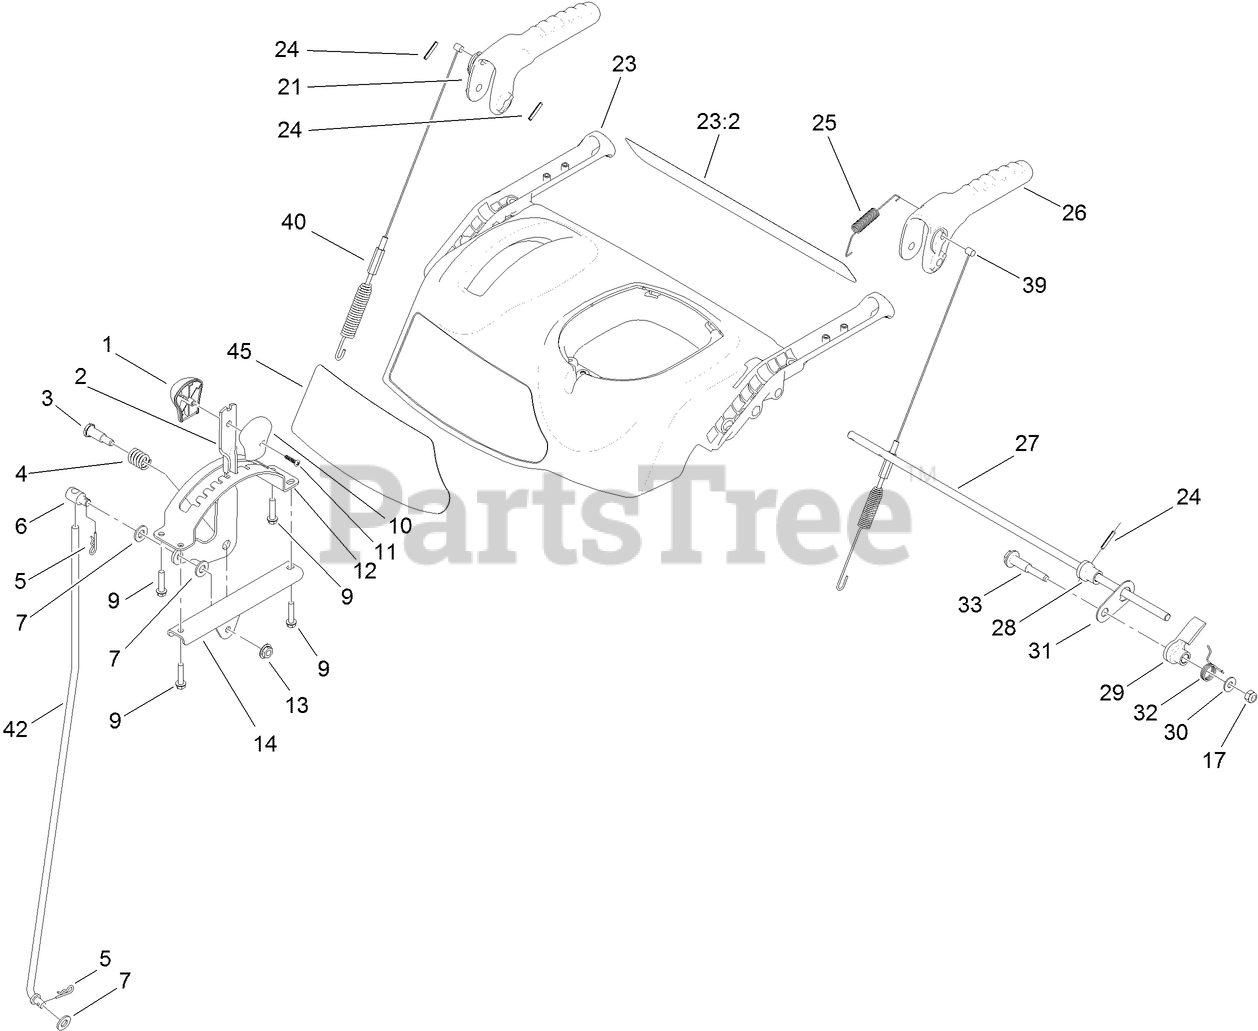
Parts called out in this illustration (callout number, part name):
1	KNOB-SHIFT, RH
2	SELECTOR-SPEED
3	SCREW-SHOULDER
6	TRUNNION-ROD
7	WASHER-FLAT
9	SCREW-PLASTITE
10	KNOB-SHIFT, LH
11	SCREW-PPH
12	GUIDE-SELECTOR, SPEED
13	NUT-HF
14	MOUNT-SELECTOR, SPEED
17	NUT-LOCK, NI
21	LEVER-AUGER
23	CONTROL PANEL ASM
23:2	DECAL-PANEL, CONTROL
24	PIN-SPRING
25	SPRING-TENSION
26	LEVER-TRACTION
27	ROD-LOCKOUT
28	CAM-LOCKOUT
29	LATCH-LOCKOUT
30	WASHER-FLAT
31	LINK-LOCKOUT
32	SPRING-TORSION
39	CABLE-TRACTION
40	CABLE-AUGER
45	DECAL-CONTROL PANEL
